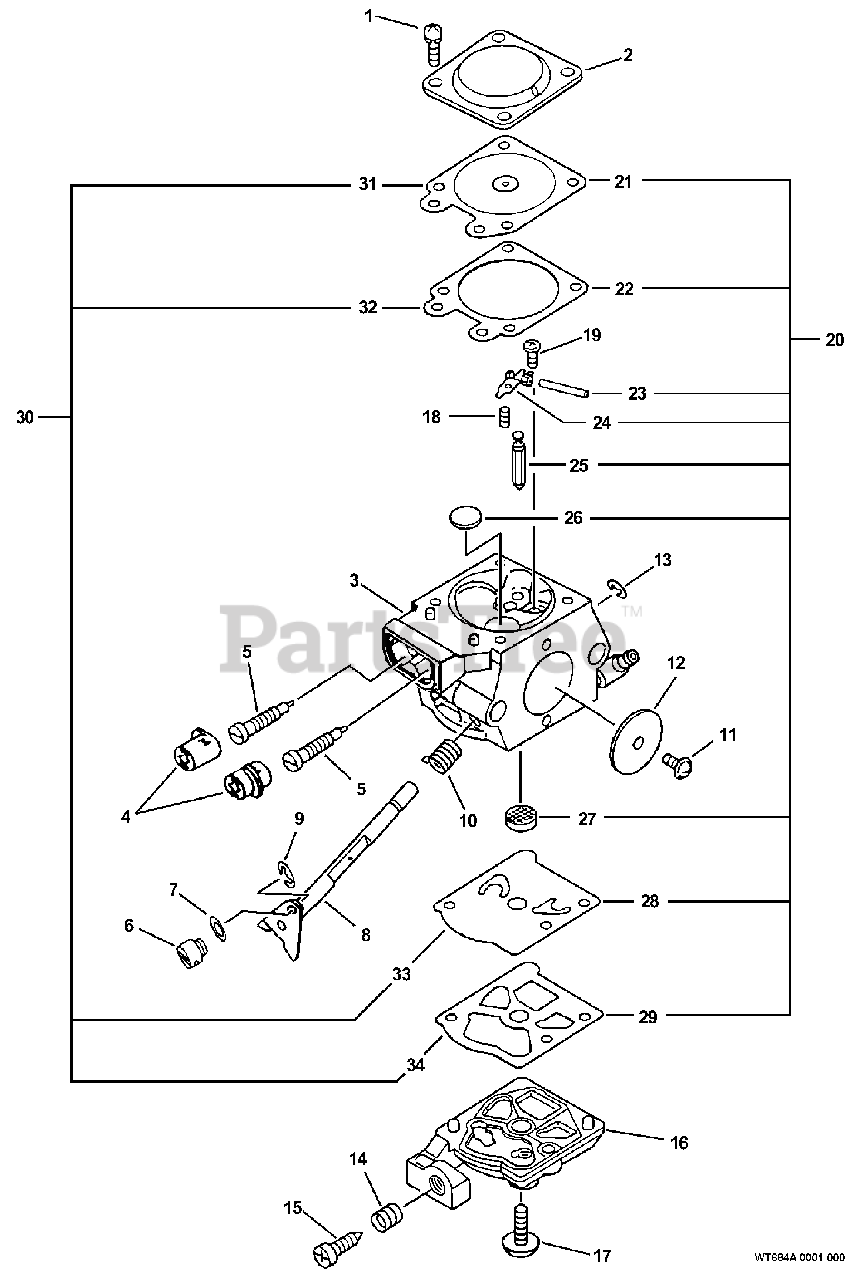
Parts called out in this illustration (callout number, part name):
2	COVER, METERING
3	BODY, CARBURETOR
4	CAP, LIMITER
5	NEEDLE - MIXTURE
8	SHAFT, THROTTLE
9	RING, RETAINING
10	SPRING, THROTTLE RETURN
12	VALVE, THROTTLE
13	RING, RETAINING
14	SPRING, IDLE ADJUST
15	SCREW, IDLE ADJUST
16	COVER, PUMP
17	SCREW, PUMP COVER
18	SCREW, METERING LEVER PIN
19	SPRING, METERING LEVER
20	REPAIR KIT
21	DIAPHRAGM, METERING
22	GASKET, DIAPHRAGM
23	PIN, METERING LEVER
24	LEVER, METERING
25	VALVE, INLET NEEDLE
26	PLUG, WELCH
27	STRAINER
28	DIAPHRAGM, PUMP
29	GASKET, PUMP
30	DIAPHRAGM/GASKET KIT
31	DIAPHRAGM, METERING
32	GASKET, DIAPHRAGM
33	DIAPHRAGM, PUMP
34	GASKET, PUMP
